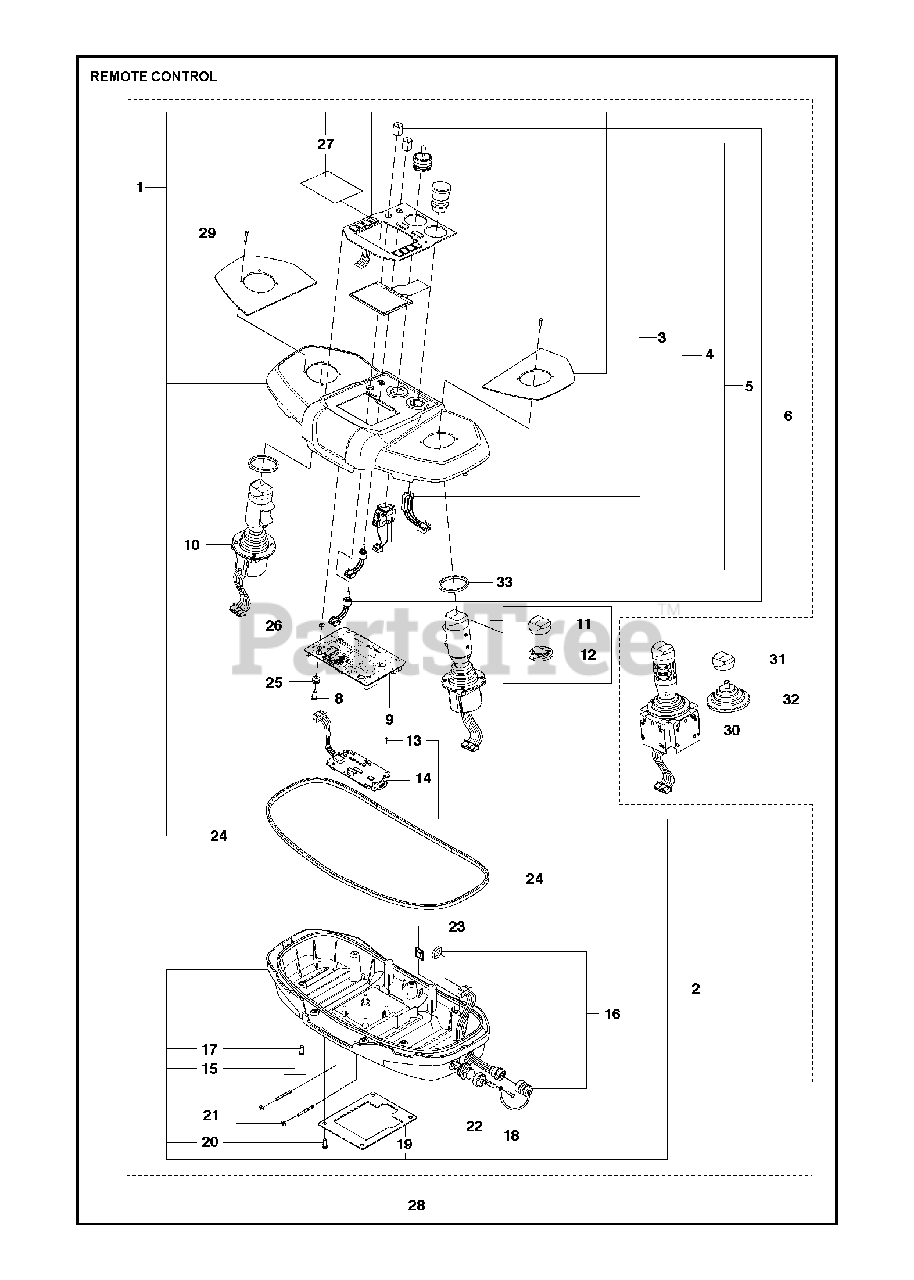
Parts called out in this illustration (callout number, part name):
4	SWITCHMain switch, ON/OFF
9	CONTROL BOARDNo firmware installed
14	CONTROL BOARDBluetooth
16	CONNECTIONCommunication cable
